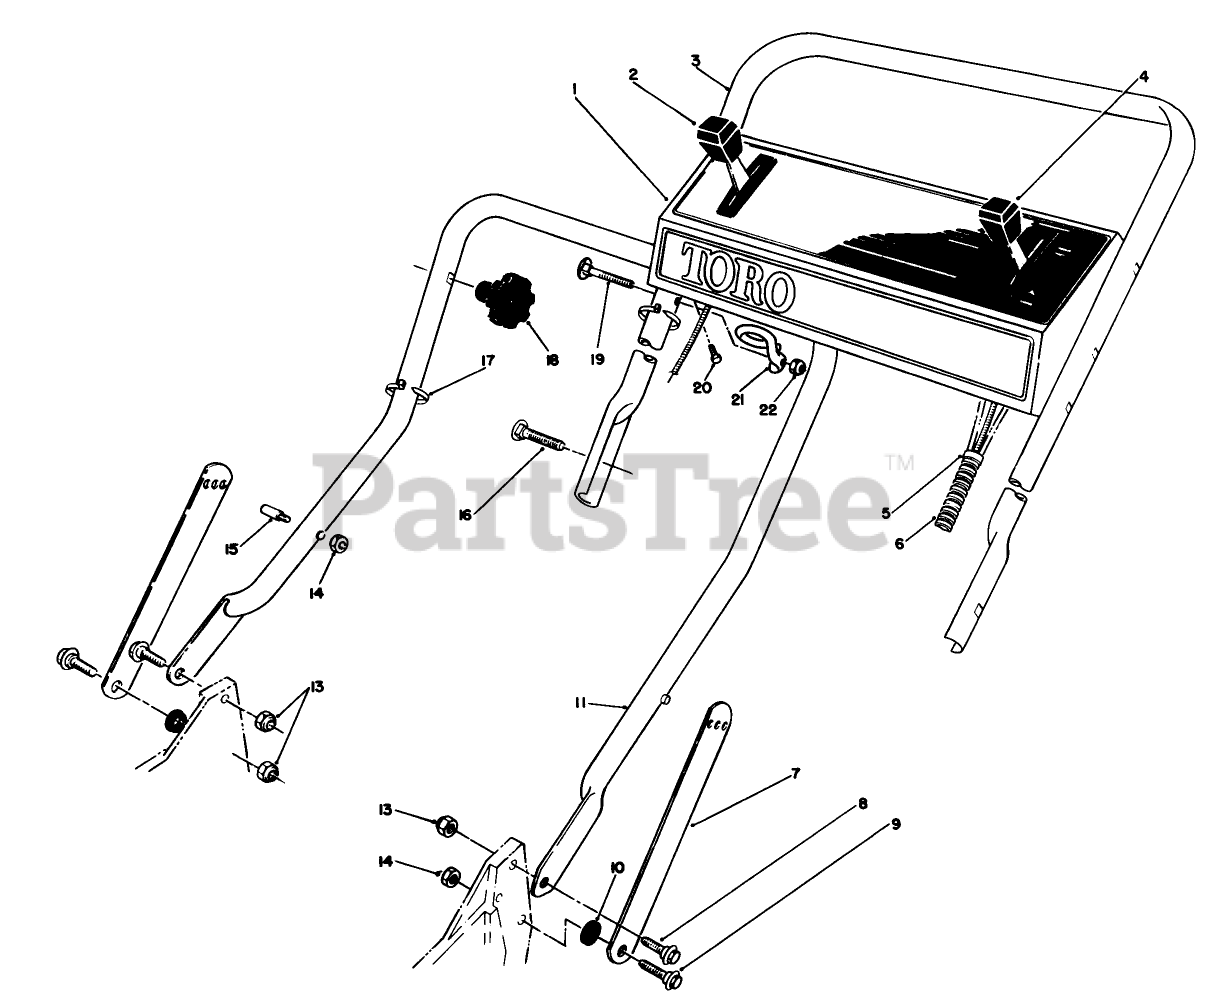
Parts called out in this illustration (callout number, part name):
4	THROTTLE CONTROL
5	FITTING-RING
8	SCREW-SHOULDER
9	SCREW-SHOULDER
10	SPACER
13	NUT-LOCK, NI
14	NUT-LOCK, NI
15	HANDLE PIN
17	TIE-CABLE
19	HANDLE SCREW
20	SCREW-HWHTF
22	NUT-LOCK, NI
